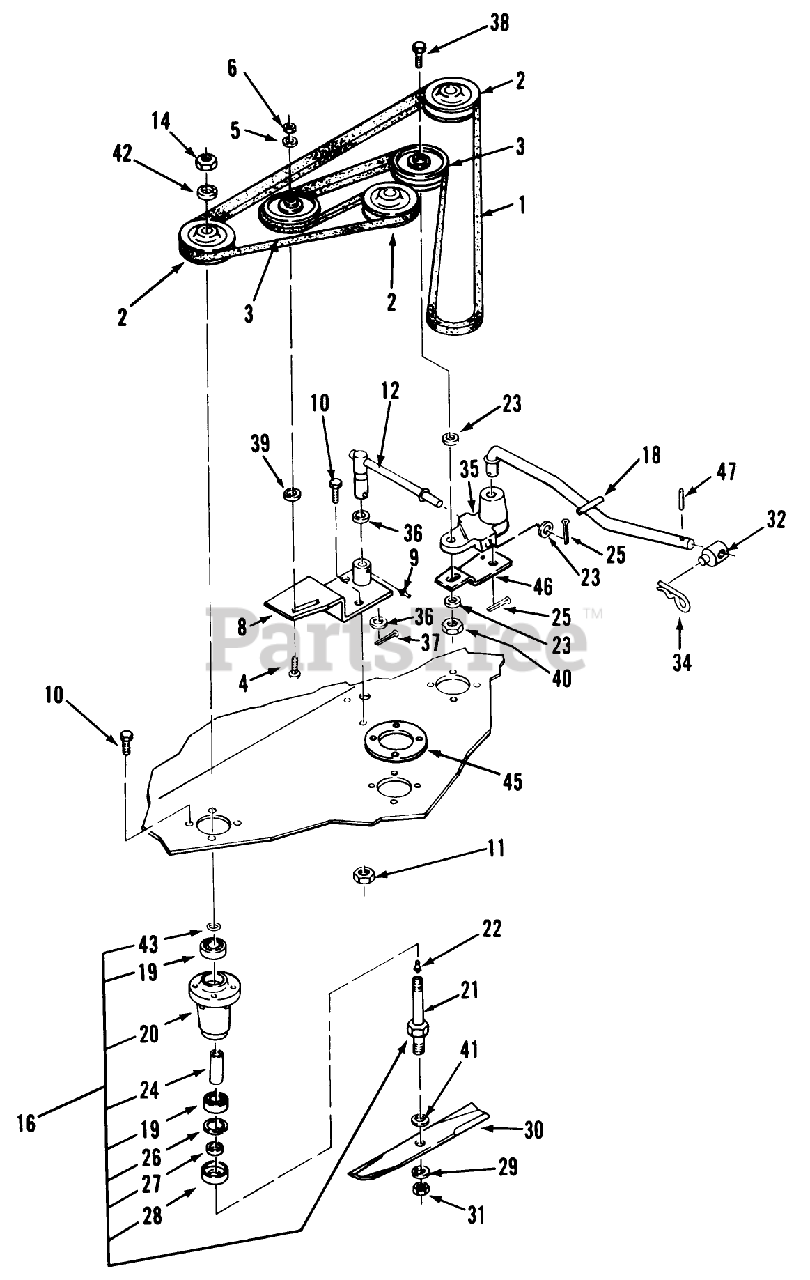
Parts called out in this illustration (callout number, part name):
1	BELT-MOWER
3	PULLEY-FLAT IDLER
9	FITTING-GREASE
18	ASS'Y-ROD IDLER
19	BEARING-BALL
20	HOUSING-SPINDLE
21	SHAFT-SPINDLE
26	Ring-Snap
27	SPACER-BLADE
30	S/A BLADE KIT
32	TRUNNION-LIFT
34	Hairpin Cotter
35	BLOCK IDLER
36	WASHER
43	O RING
45	PLATE-SPINDLE
